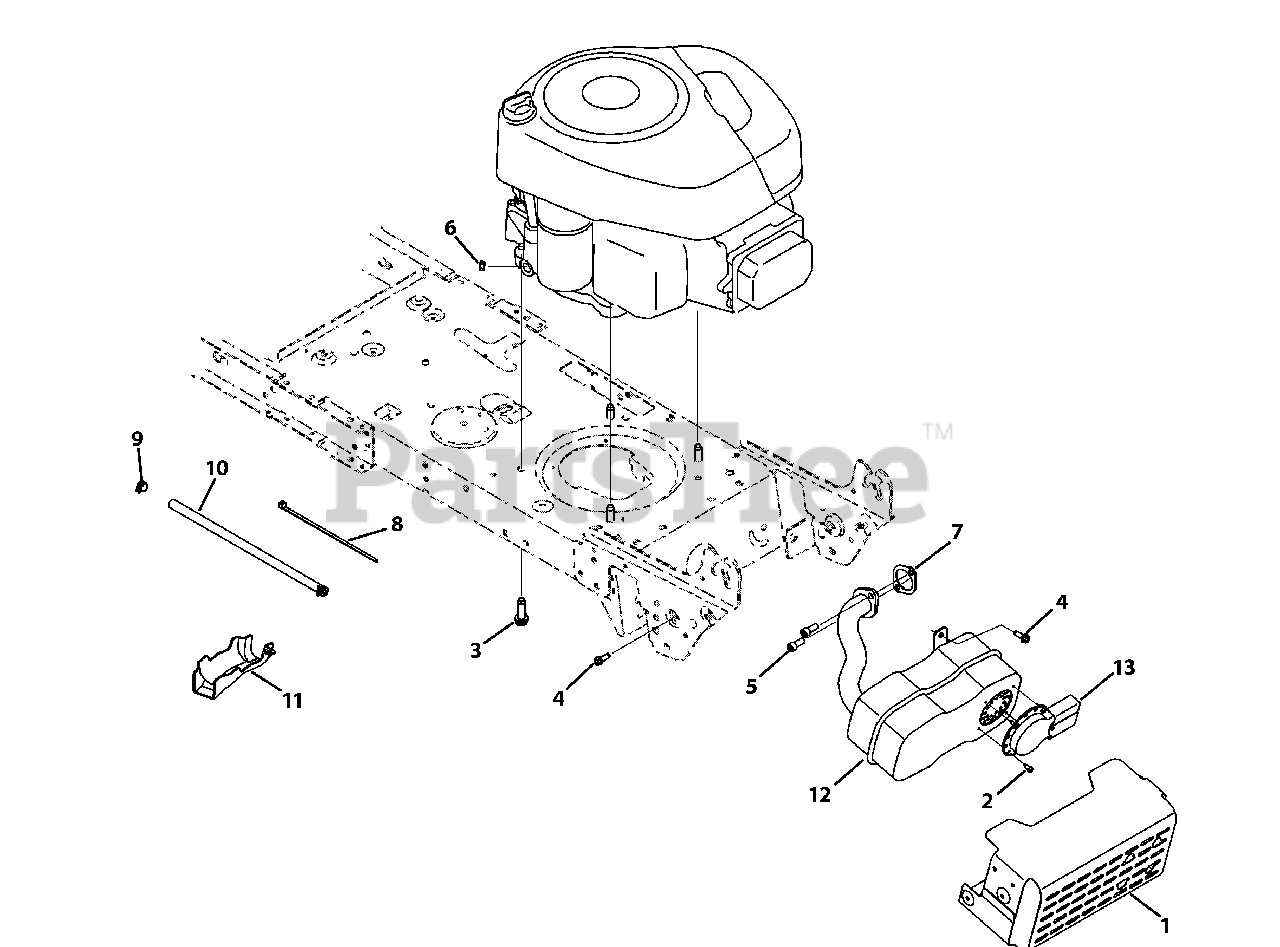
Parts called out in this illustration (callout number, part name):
1	Muffler Shield Assembly with Weld
2	Screw, 8-18 x .500
3	Screw, 3/8-16 x 1.0
4	Screw, 1/4-20 x .750
5	Socket Screw, 5/16-18 x .750
6	Sems Nut, 1/4-20
7	Exhaust Gasket, 10 HP Briggs
8	Cable Tie
9	Clamp Hose, .490 diameter
10	Fuel Hose, Low Permeation
11	Oil Drain Sleeve
12	Muffler, Single Inlet
13	Muffler Deflector Long
